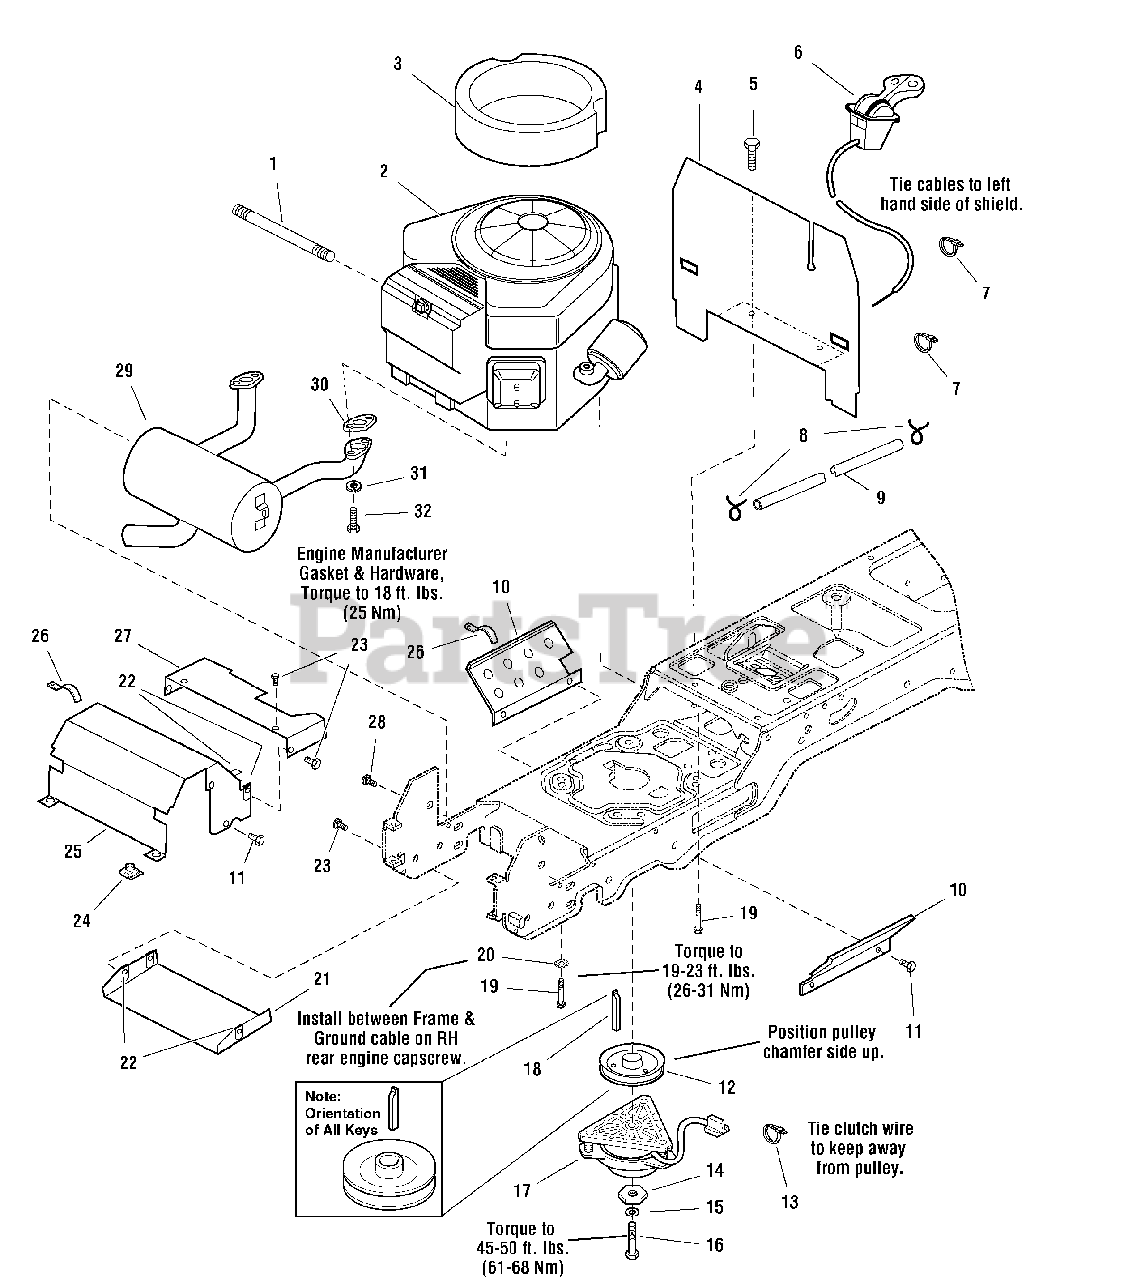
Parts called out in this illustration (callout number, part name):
1	HOSE, Oil Drain, 10 1/2 Long, 3/8-18 Fittings
3	SEAL, Circle
4	BULKHEAD
5	CAPSCREW, Hex Washer Head Taptite, 1/2-20 x 1/2, Black
6	CONTROL, Throttle Double 39" Long w/Knobs
7	TIE, Wire
8	CLAMP, Hose Type E
9	HOSE, Fuel, 58 Long
10	SHIELD, Side
11	CAPSCREW, Hex Washer Head Taptite, 1/4-20 x 3/8
12	PULLEY & HUB ASSEMBLY
13	TIE, Self Locking, 3-5/8 Long
14	WASHER, Hex, 7/16, Black
15	LOCKWASHER, 7/16
16	CAPSCREW, Hex Head, 7/16-20 x 3-1/2
17	CLUTCH, Electric
18	KEY, HI PRO, 1/4 x 2 1/2
19	CAPSCREW, Hex Washer Head Taptite, 3/8-16 x 1-1/2
20	LOCKWASHER, External Tooth, 3/8
21	SHIELD, Muffler Bottom
22	NUT, Speed, 1/4-20, Lug
23	CAPSCREW, Hex Flange Whiz Lock, 1/4-20 x 5/8
24	NUT, Speed, Lug Type, 5/16-18
25	DUCT, Muffler Top
26	CLIP, Wire 1/8
27	DUCT, Muffler Extension
28	CAPSCREW, Hex Washer Head Taptite, 5/16-18 x 1/2 Black
29	MUFFLER, Briggs & Stratton, Vanguard Twin
30	* GASKET, Briggs & Stratton, Vanguard Twin
31	LOCKWASHER, 1/4
